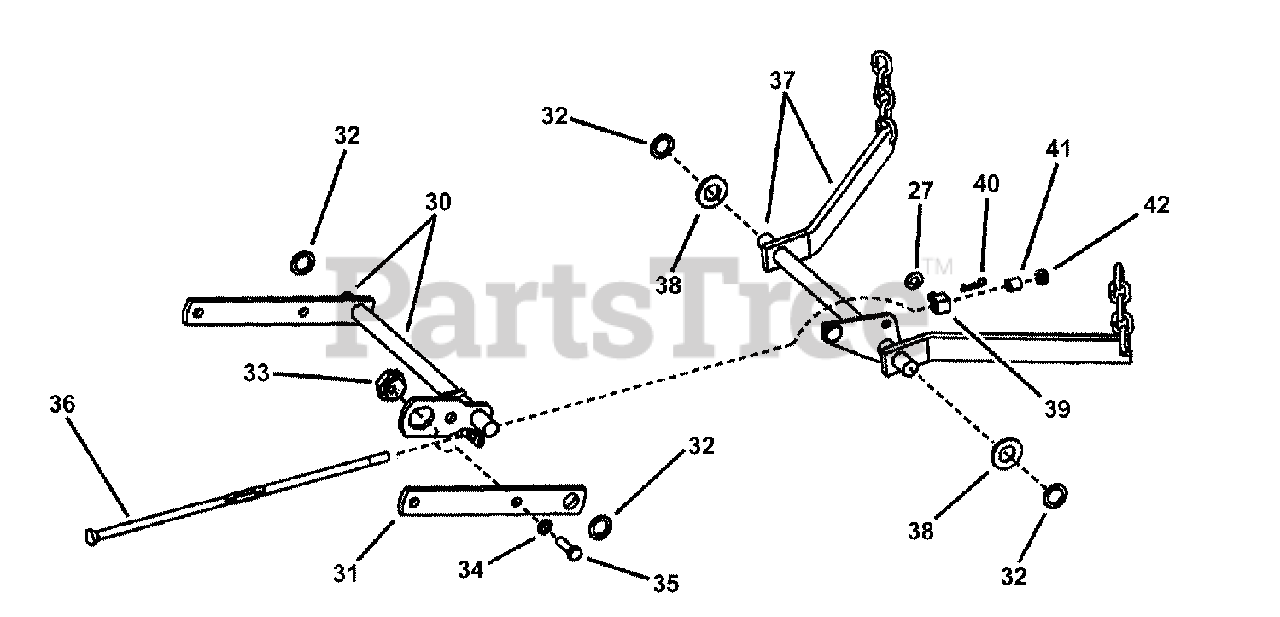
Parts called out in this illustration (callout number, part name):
27	WASHER, 3/8" SAE Flat
28	NUT, 3/8-24 Hex Center Lock
29	WASHER, .27 x 1.0 x .065 Flat
30	WELDMENT, Lift Arm, Front
31	LIFT ARM, Front
32	WASHER, 3/4" Flat
33	ECCENTRIC, Leveling
34	WASHER, 3/8" Internal Tooth Lock
35	SCREW, 3/8-24 x 1-1/4" Hex Head Cap w/Nylon Patch, GR5
36	ROD, Cutter Deck Timing (3/8-16 thread)
37	WELDMENT, Lift Arm, Rear
38	WASHER, .781 x 1.5 x .132 Flat
39	SWIVEL, Brake Link- PM
40	HAIR PIN, #13
41	SPACER, .391 I.D. x .531 long
42	NUT, 3/8-16 Hex Center Lock
